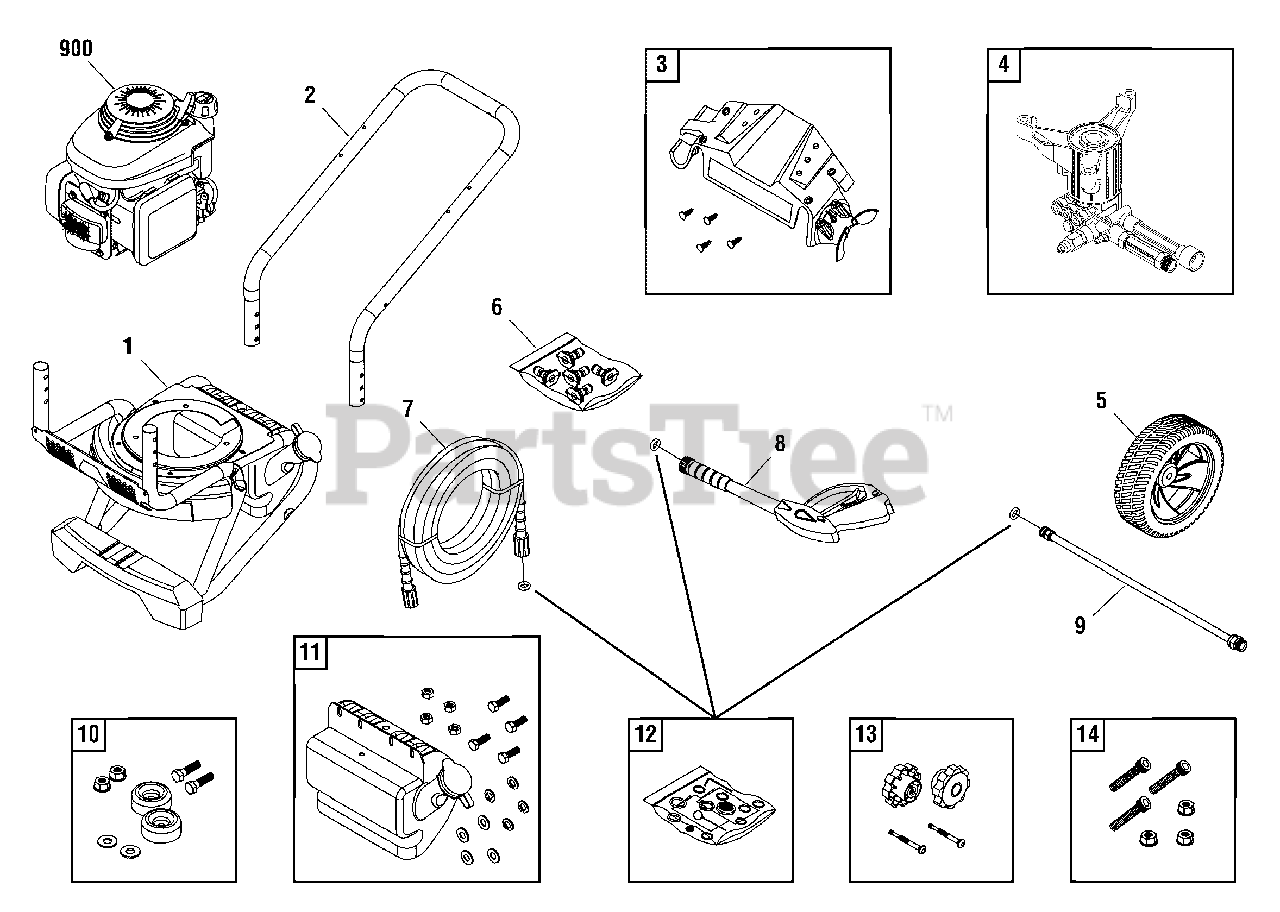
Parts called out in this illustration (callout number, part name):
6	KIT, QC Nozzles
7	HOSE
8	GUN
9	EXTENSION, QC
10	MOUNT, Vibration
12	KIT, O-Rings
13	KIT, Hardware, Handle
14	KIT, Hardware, Pump Mounting
900	* ENGINE
